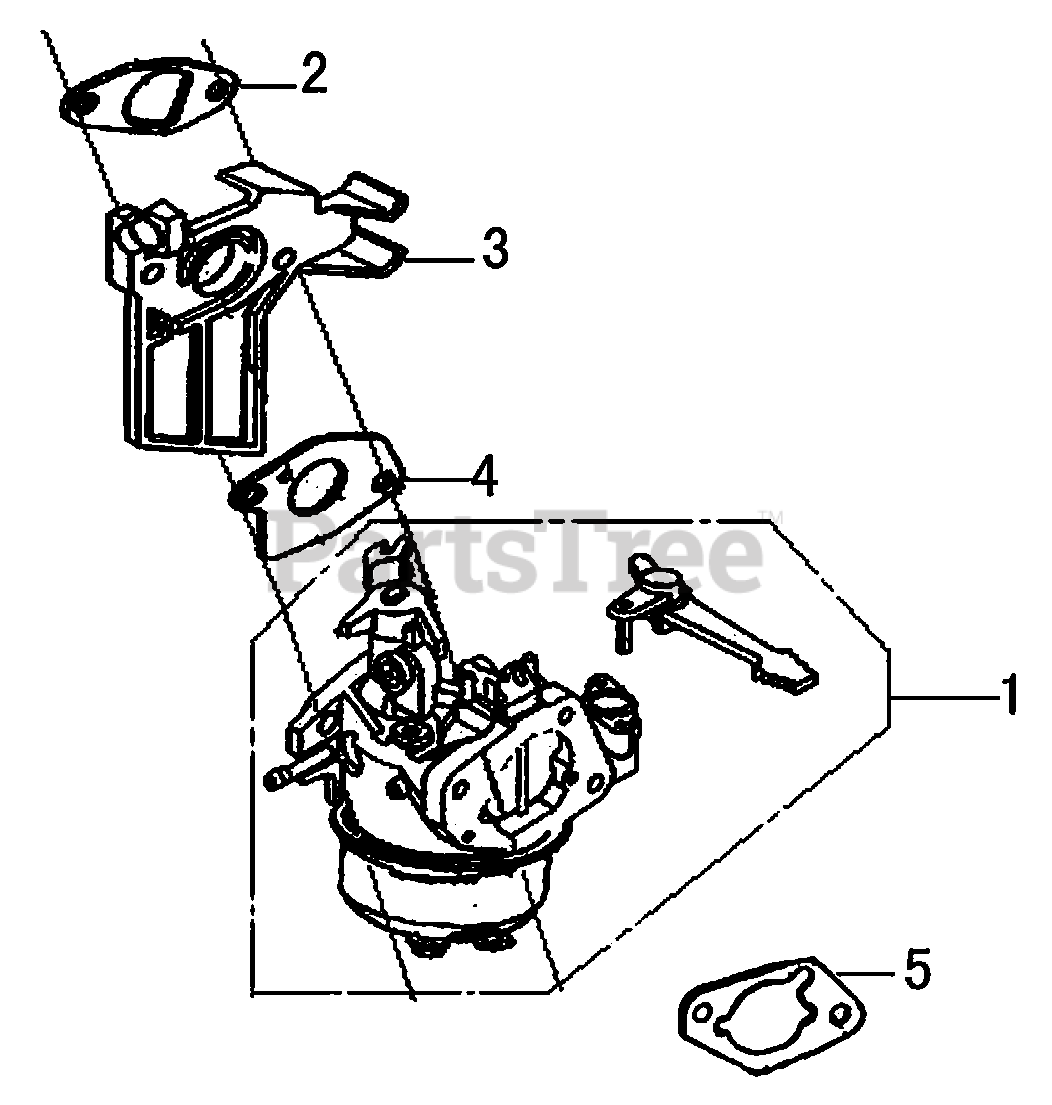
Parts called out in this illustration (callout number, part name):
1	CARBURETOR
2	GASKET, INSULATOR
3	INSULATOR, CARBURETOR
4	GASKET, CARBURETOR
5	SPACER, AIR CLEANER
